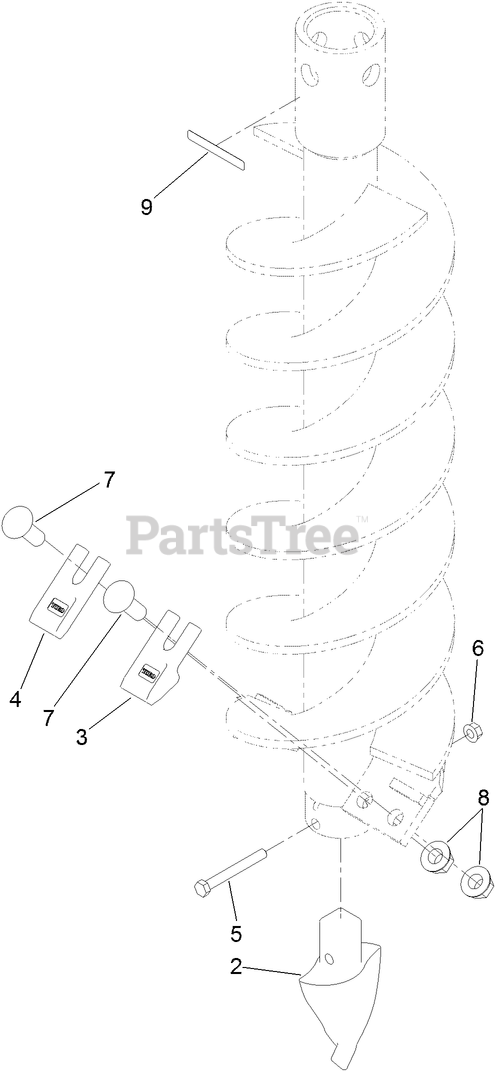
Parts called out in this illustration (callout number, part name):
2	PILOT-AUGER
3	TOOTH-OUTER
4	TOOTH-INNER
5	SCREW-HH
6	NUT-HF
7	SCREW-CARR
8	NUT-FLANGE
9	DECAL-WARNING
